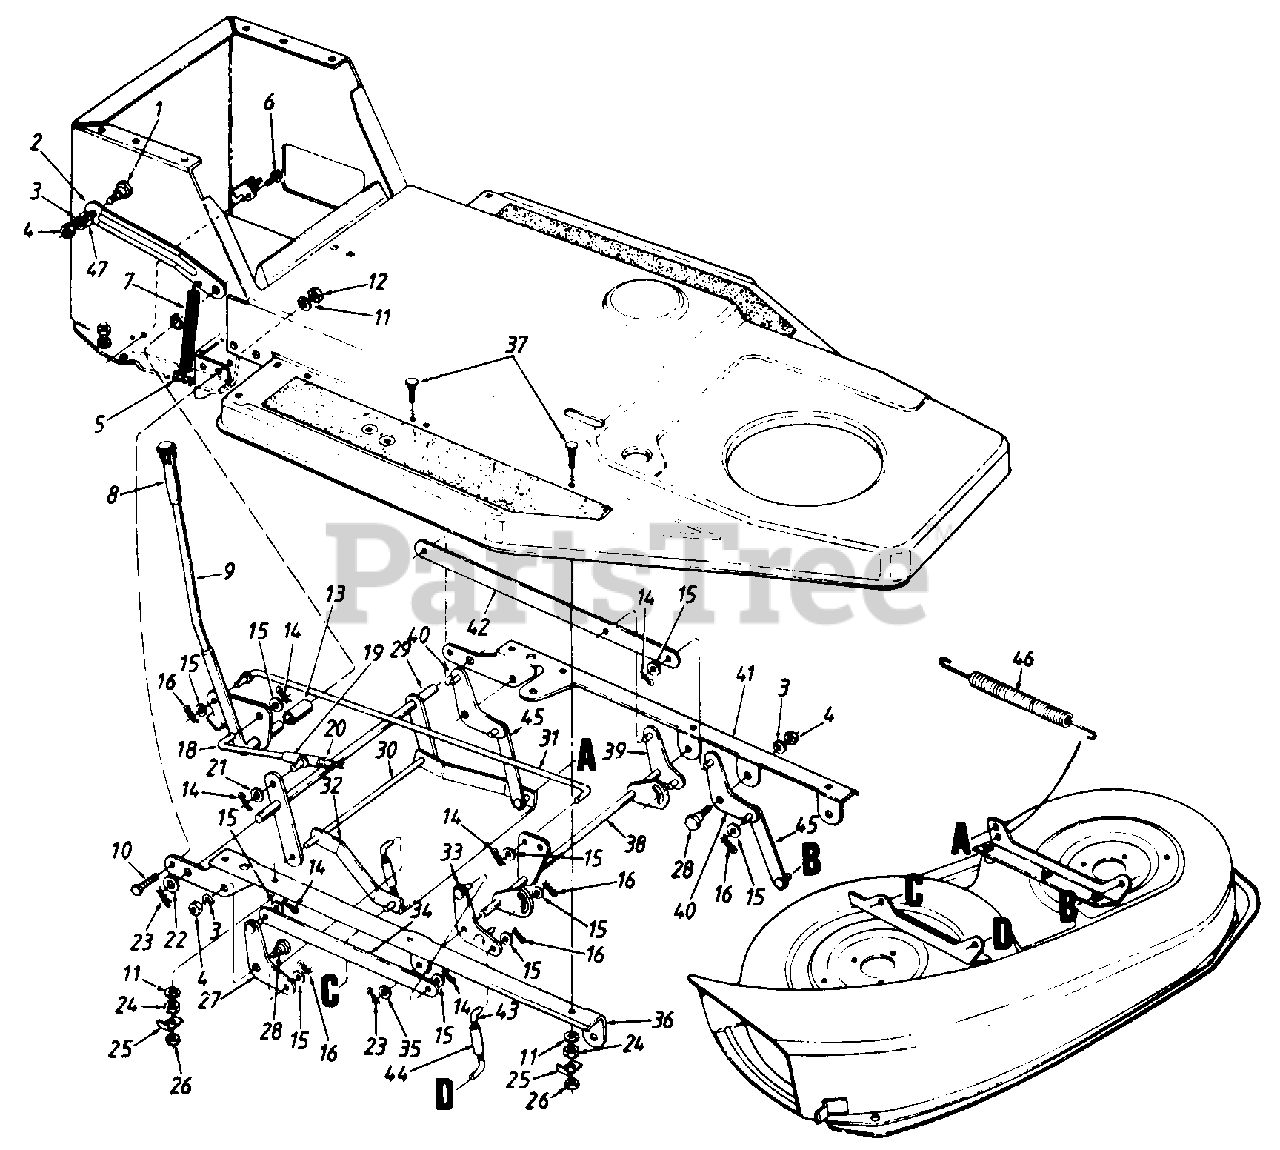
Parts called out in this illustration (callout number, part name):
1	Shld. Bolt .5" Dia. x .34" Lg.
4	Hex Nut 3/8-16 Thd.
5	Hex Bolt 1/4-28 x 1.25" Lg.
6	Hex Wash. Hd. TT-Tap Scr. 1/4-20 x .5" Lg.
9	Deck Lift Handle Ass'y.
10	Hex Wash. TT-Tap Scr. 5/16-18 x .62" Lg.
11	L-Wash. 5/16" I.D.
12	Hex Nut 5/16-18 Thd.
13	Spacer 5/8" I.D. x .78"
14	Cot-Pin 3/32" Dia. x .75" Lg.
15	Fl-Wash. .406" I.D. x .75" O.D.
16	Internal Cot-Pin 5/16" Dia.
18	Deck Engagement Rod
19	Pivot Sleeve Ass'y.
20	Hex L-Nut 3/8-16 Thd.
21	Thrust Washer .382" I.D.
22	Fl-Wash. .635" I.D. x .93" O.D.
23	Cot-Pin 1/8 Dia. x 1.25" Lg.
24	Hex Nut 5/16-24 Thd.
25	Harness Retainer
26	Hex Cent. L-Nut 5/16-24 Thd.
27	Deck Pivot Brkt. Ass'y. - R.H. Rear
28	Shld. Bolt .625" Dia. x .170" Lg.
31	Deck Lift Rod
32	Deck Stabilizer Brkt.
44	Adj. Lift Link Ass'y.
45	Deck Lift Link Ass'y.
46	Deck Spring 10.33" Lg.
47	Fl-Wash. .531" I.D. x .94"
